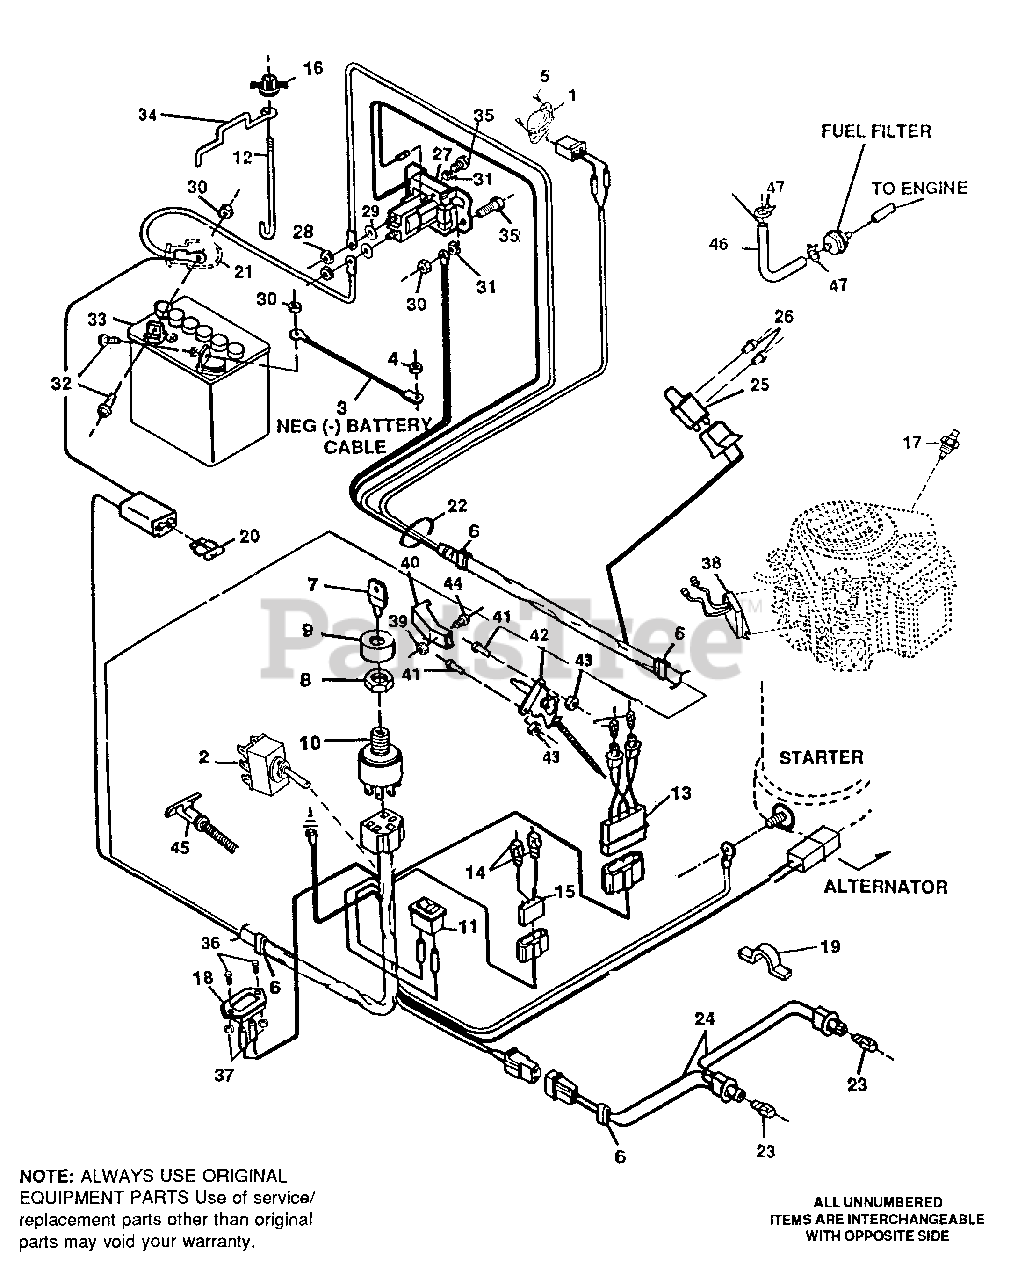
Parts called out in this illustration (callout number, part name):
1	Seat Switch
2	Switch, Elec./Clutch Actuator
3	Cable, Battery, Negative
4	Nut, Hx, Keps, 5/16-18 Thd.
5	Screw, 1 /4-20 x .38
6	Tie Cable
7	Key, Ignition Switch
8	Nut, Switch
9	Boot, Switch
10	Switch, Ignition
11	Switch, Light
12	Rod, Battery Hold-Down
13	Lamp Holder,Low Fuel and Oil Pressure
14	Bulb,lndicator
15	Lamp Holder,All Systems Go and Charge
17	Oil Sensor
18	Minature Hour Meter
19	Press Clip
20	Fuse, 15A-32V, Spade Type
21	Boot, Rubber (Battery Cable)
22	Wire Harness
23	Bulb Headlamp
24	Assembly, Light Wire
26	Screw, Pn Hd, Tap #12 x 1/2 In.
27	Solenoid
28	Nut, Hx 5/16-24 Thd.
29	Washer, Lock 5/16 In.
30	Nut, Hx, Keps, 1/4-20 Thd.
31	Nut, Hx, Ctrlk, 1/4-20 Thd.
32	Screw, 1/4-20 x 5/8 In.
34	Bracket, Battery Hold-Down
35	Screw, 1/4-20 x 3/4 In.
36	Screw, #6-32 x .50
37	Nut, Hx Keps 6-32
38	Regulator, Sen. Volt BS with Sensor
39	Nut, Hex. #8-32 Thd.
40	Knob, Throttle Control
41	Screw #10-24 x 5/8
42	Throttle Control
43	Nut, Hex, Nylon Lock #8-32 x 3/8 In.
44	Screw,Ph, Pn, #8-32 x 3/8 In.
45	Choke Control
46	Gas Line
47	Clamp, Gas Line
